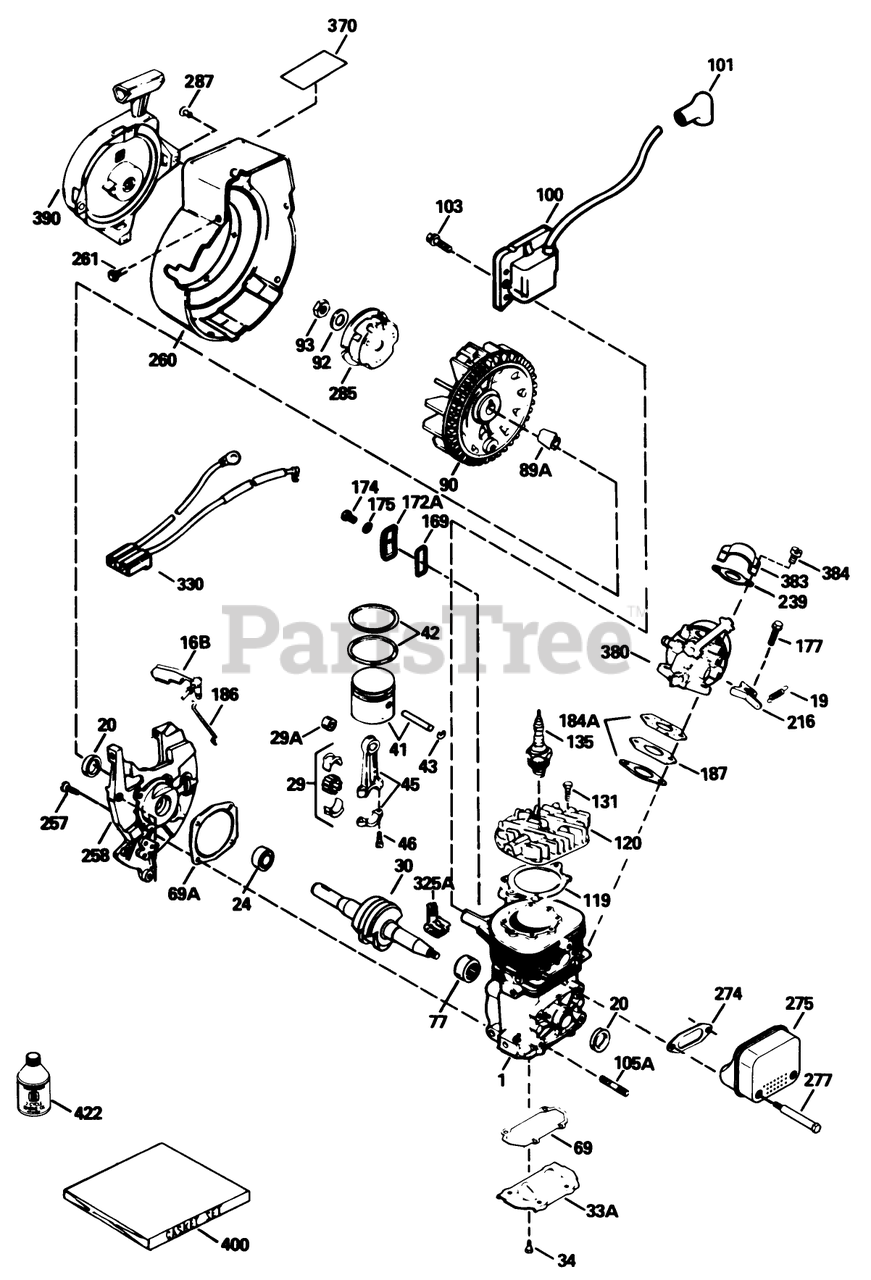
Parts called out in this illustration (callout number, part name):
1	Block Ass-y-Cylinder (Order short block if replacement is required)
16B	Vane-Air
19	Spring-Extention
20	Seal-Oil
24	Bearing-Ball
29	Needle Bearing and Liner Set (37 Needles)
29A	Bearing-Cartridge
30	Crankshaft
33A	Plate-Cover
34	Screw (T-25, 10-24 x 1/2)
41	Piston (Incl. Ref. #43)
42	Ring Set
43	Ring-Retaning
45	Rod Assy.-Connecting (Incl. Ref. #3, 3A 3B)
46	Bolt-Rod, Connecting
69	Gasket-Plate, Cover
69A	Gasket-Cover, Cylinder
77	Bearing-Cartridge
89A	Blade (20 inch)
90	CARB BODY S
92	Washer-Belleville
93	Nut-Flywheel
100	Solid State
101	Cover-Spark Plug
103	Screw
119	Gasket-Head, Cylinder
120	Head-Cylinder
131	Screw (T-30, 1/4-20 x 3/4)
135	Spark Plug-Resistor (R C J 8Y)
169	Cover-Compression, Release
172A	Comp. Release Cover
174	Screw (T-25, 10-24 x 1/2)
175	Washer
177	Screw (5/32 Allen, 1/4-20 x 1)
184A	Gasket-Carburetor
186	Link-Governor
187	Spacer
216	Lever-Adjusting, Rpm
239	2060A77 WIZARD ROTA
257	Screw (T-30, 1/4-20 x 5/8)
258	Base Ass-y-Blower Housing (Incl Ref. #20)
260	Housing-Blower
261	Screw (1/4-20 x 1/2)
274	Gasket-Exhaust
275	Muffler (Incl. Ref. #274 277)
277	Screw (1/4-20 x 2-3/4)
285	Cup-Starter
287	Rivet-Pop
325A	Clip-Wire
330	Harness-Wire
370	Decal-Warning
380	Carburetor (Incl. Ref. #184A)
383	Baffle-Carburetor
384	Screw
390	Starter-Rewind
400	Gasket Set
422	2-Cycle Oil (8oz)
